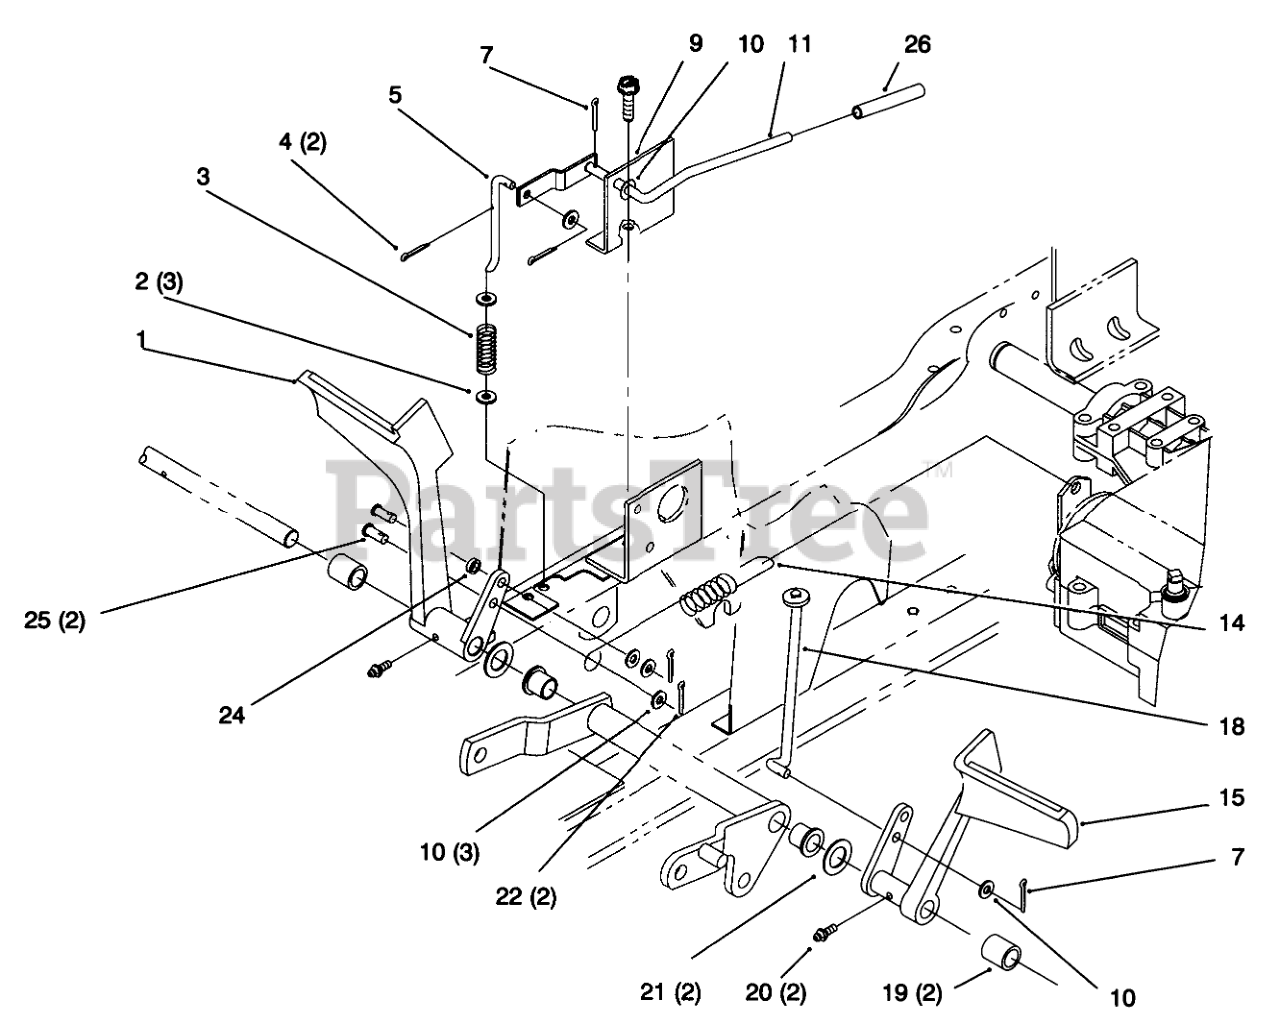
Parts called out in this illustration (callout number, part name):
1	Pedal-Brake (Only On: 72042, 72062)
2	Washer-Flat (Only On: 72042, 72062)
3	Spring-Compression (Only On: 72042, 72062)
4	Pin-Cotter (Only On: 72042, 72062)
5	Rod-Park Brake (Only On: 72042, 72062)
7	Pin-Cotter (Only On: 72042, 72062)
9	Bracket-Parking Brake (Only On: 72042, 72062)
10	Washer-Flat (Only On: 72042, 72062)
11	Lever-Parking Brake (Only On: 72042, 72062)
14	Spring-Extension (Only On: 72042, 72062)
15	Pedal-Clutch (Only On: 72042, 72062)
18	Rod-Clutch (Only On: 72042, 72062)
19	Spacer (Only On: 72042, 72062)
20	Fitting-Grease (Only On: 72042, 72062)
21	Washer-Wave (Only On: 72042, 72062)
22	Pin-Cotter (Only On: 72042, 72062)
24	Spacer (Only On: 72042, 72062)
25	Pin-Clevis (Only On: 72042, 72062)
26	Grip-Parking Brake (Only On: 72042, 72062)
